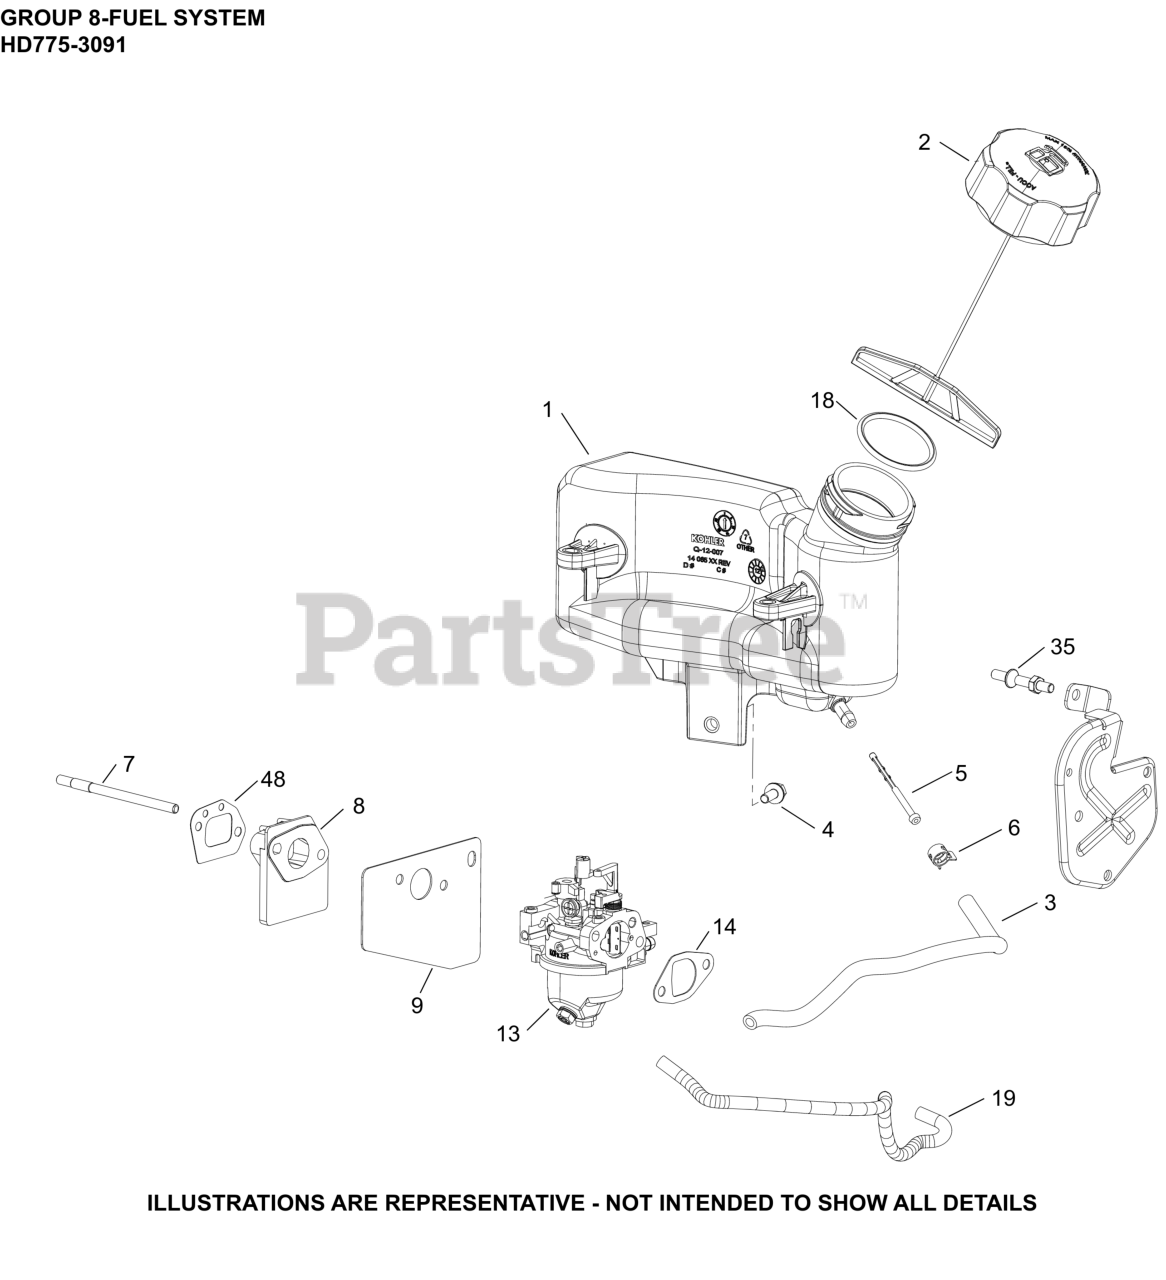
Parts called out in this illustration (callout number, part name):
1	TANK, FUEL 1.4L FOR EUROPE ONLY
2	CAP ASSEMBLY, FUEL
3	HOSE, FUEL LOW-PERMEATION
4	SCREW, HEX FLANGE (M6)
5	FILTER, FUEL IN-NIPPLE
6	CLAMP, HOSE (NON-CALIF)(#1423710S)
7	STUD,M6X1.0X100.2MM
8	KIT, SPACER
9	KIT, CARBURETOR HEAT SHIELD GASKET
13	KIT, CARBURETOR 13 MM STD CHOKE
14	KIT, INTAKE GASKET
18	SEAL, FUEL CAP- (#DSC)
19	HOSE, EVAPORATIVE
48	GASKET SPACER
NI	TOOL, SPARK PLUG WRENCH ASSY
NI	KIT,HIGH AL(4000-8000 FT)USE 14 755 04-S
NI	KIT, CARBURETOR REPAIR (RUIXING)
